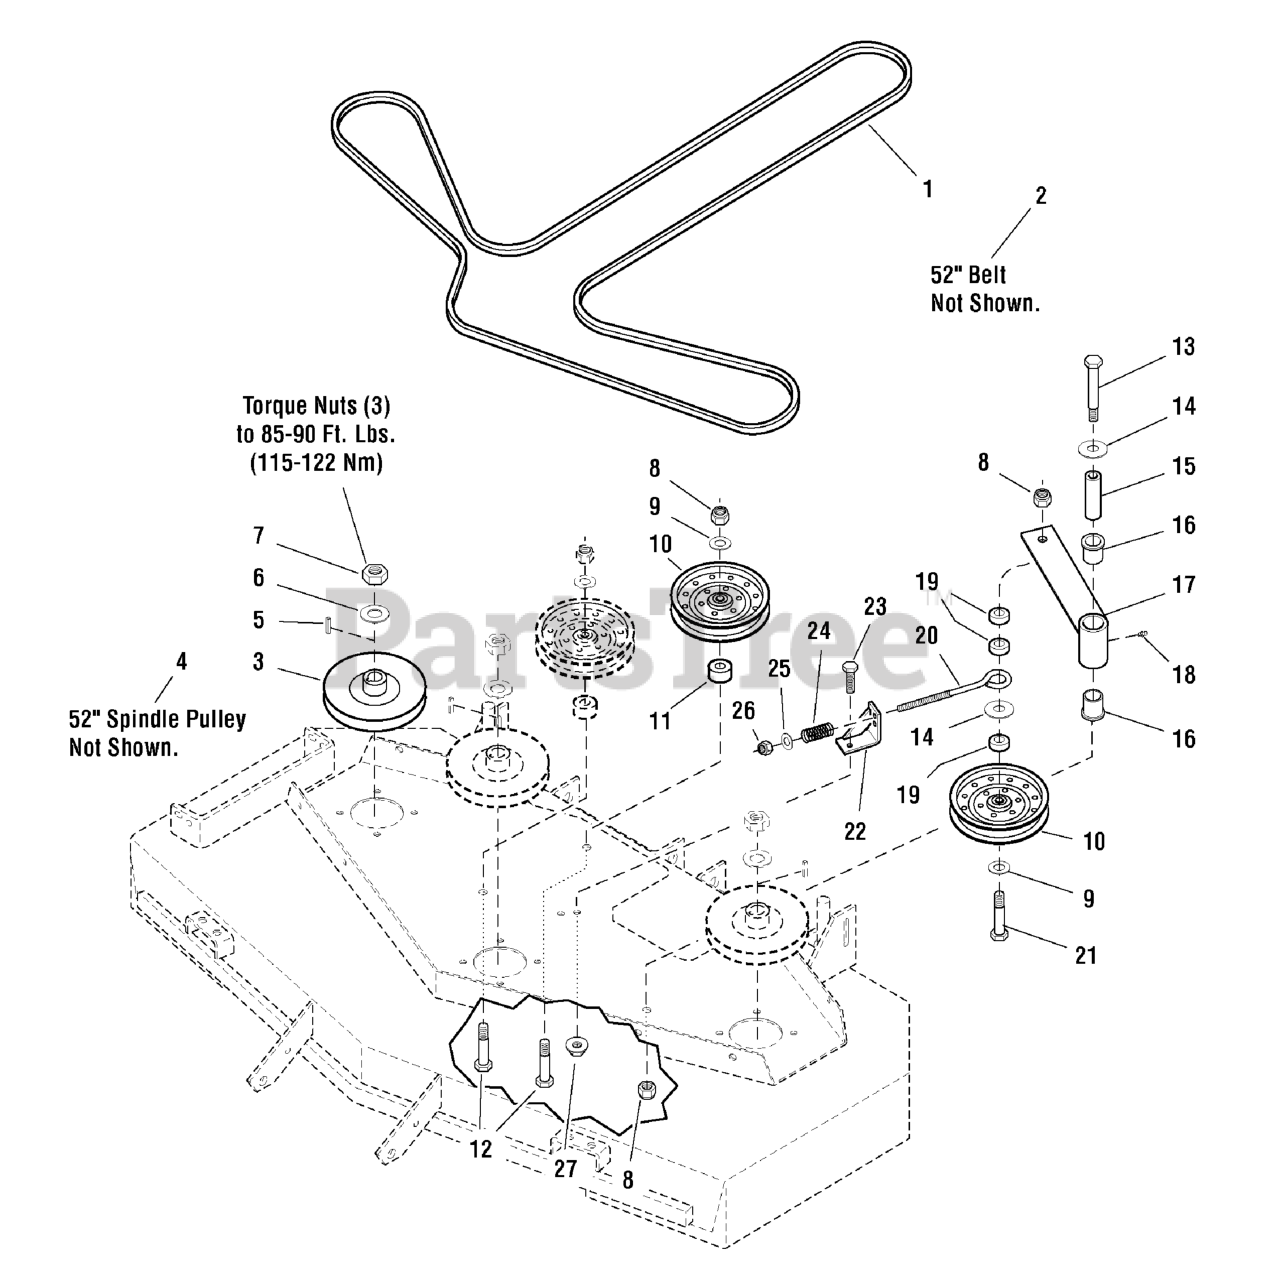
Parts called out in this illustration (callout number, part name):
1	BELT (48" Deck)
3	PULLEY, 5.540OB X .985ID, SINGLE B-SEC
5	KEY, 1/4 SQ. X 1-1/4
6	WASHER, 3/4 BELLEVILLE
7	NUT, 3/4-16 Hex
8	NUT, 1/2-13 HEX NYLON LOCK
9	WASHER, 1/2 SAE
11	SPACER, .52 x 1.25 x .70
12	BOLT, 1/2-13 X 3" GD5 CZ
13	BOLT, 1/2-13 x 4-1/2
14	WASHER, 1/2" USS
15	SPACER, .52 x 1.00 x 3.50
16	BUSHING, FLANGE
17	ASSM, IDLER ARM
18	GREASE FITTING
19	SPACER, .52 x 1.00 x .44
20	EYEBOLT, 3/8" x 8"
21	BOLT, 1/2-13 X 3-1/2, HEX HD, GD5, CZ (SV)
22	SPRING ANCHOR
23	BOLT, 3/8-16 X 1" GD5 CZ
24	SPRING, Compression
25	WASHER, 3/8 SAE
26	NUT, 3/8-16 HEX NYLON LOCK
27	NUT, 3/8-16 Hex Serrated Flange
